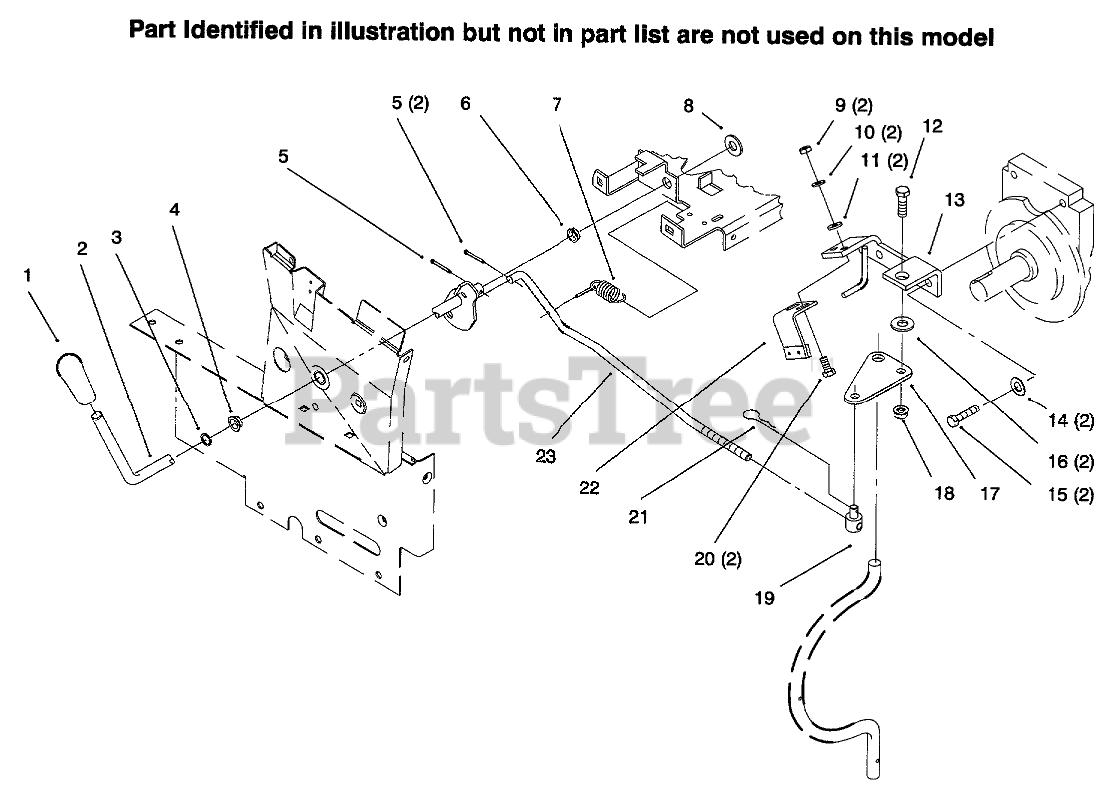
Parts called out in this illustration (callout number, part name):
2	PTO CLUTCH LEVER ASM
3	RING-EXT GRIP
4	BUSHING-NYLINER
5	PIN-COTTER
6	NYLINER BUSHING
7	SPRING
8	SHIM-WASHER
9	NUT-JAM
10	WASHER-LOCK
11	WASHER-FLAT
12	SCREW-HH
13	BRACKET WA ENG. B
14	WASHER-LOCK
15	SCREW-HH
16	SPACER-LIFT LINK
17	PLATE
18	NUT-LOCK, NI
19	TRUNNION
20	SCREW-CARR
21	PIN-HAIR
22	ASM-Bracket
22	BRAKE ASM
23	ROD-PTO CLUTCH
